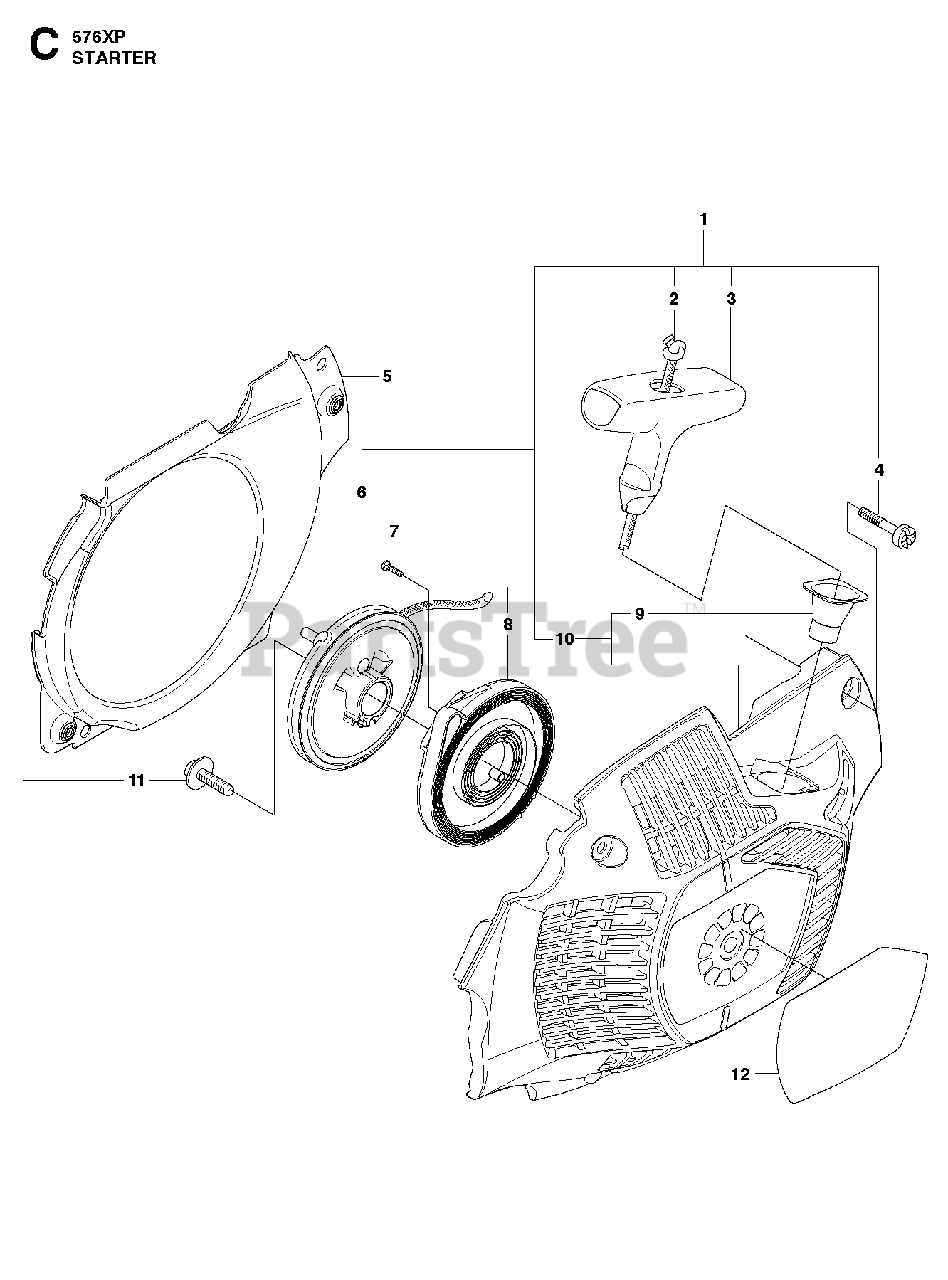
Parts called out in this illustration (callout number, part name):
1	STARTER ASSY
2	STARTER ROPE
3	HANDLE
4	SCREW
5	PLATE
6	STARTER PULLEY
7	SCREW
8	SPRING
9	SLEEVE
10	STARTER HOUSING
11	SCREW
12	LABEL
